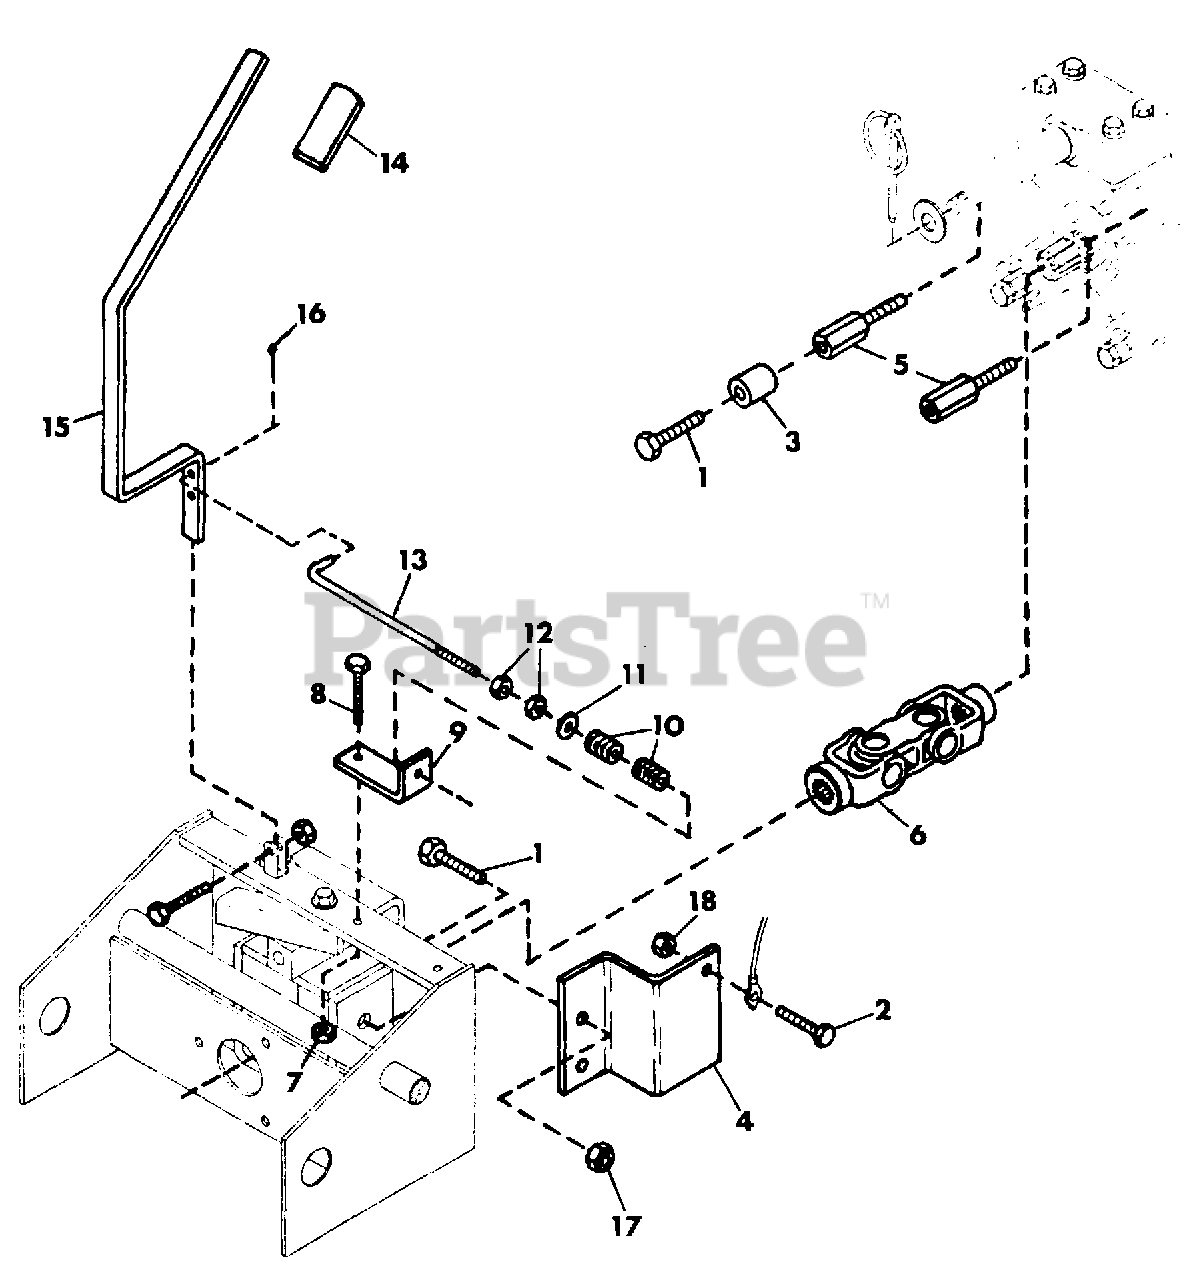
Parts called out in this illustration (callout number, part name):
1	BOLT, HEX 1/2-13X1.25
2	BOLT, HEX 5/16-18X1.00
3	BUSHING, .531X1.000X.60
4	BRACKET, LIFT
5	STUD, QUICK HITCH
6	ASM., DOUBLE JOINT
7	NUT, LOCK 3/8-16
8	BOLT, HEX 3/8-16X1.50
9	BRACKET, BELT TENSIONER
10	SPRING, COMPRESSION
11	WASHER, FLAT .406X.812X.065
12	NUT, JAM 3/8-24
13	ROD, IDLER 50" MOWER
14	GRIP, HANDLE
15	HANDLE, PRO MASTER BRUSH
16	PIN, COTTER 3/32X.75
17	NUT, LOCK 1/2-13
18	NUT, LOCK 5/16-18
